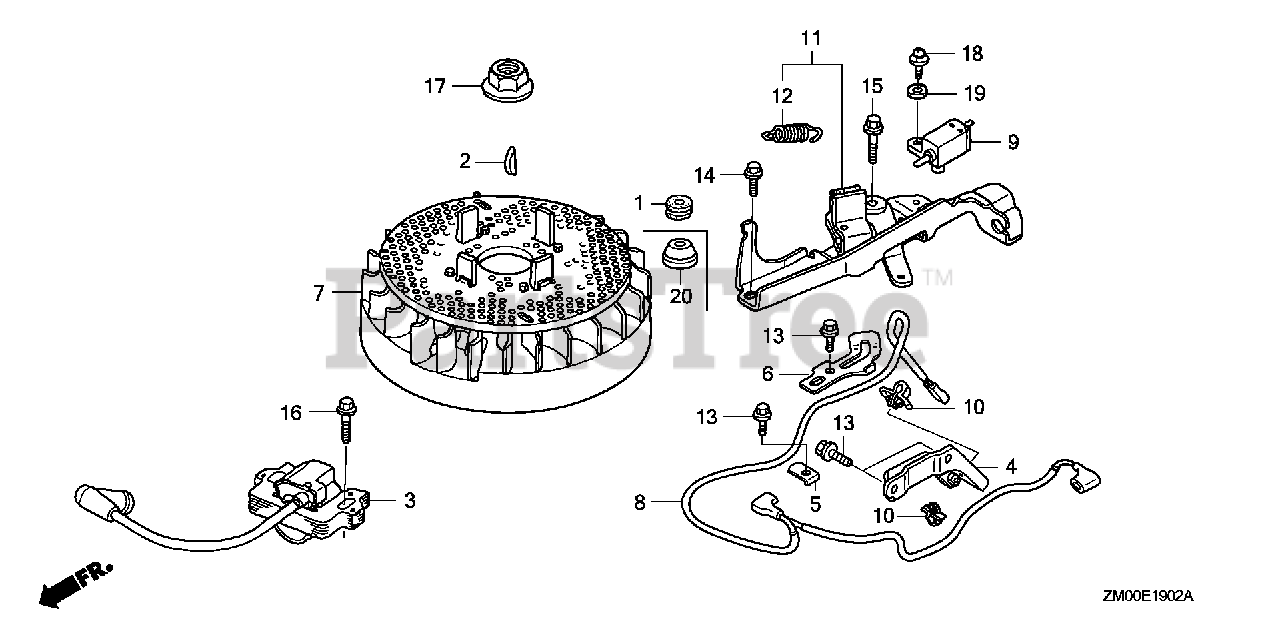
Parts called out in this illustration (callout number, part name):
1	GROMMET A, RR. COVER (8X16X6.6)
2	KEY, SPECIAL WOODRUFF (25X18)
3	COIL ASSY., IGNITION (USE FOR F/W OF TEC) (TEC)
4	CLAMP, STOP SWITCH WIRE
5	CLAMP, STOP SWITCH WIRE
6	CLAMP, WIRE
7	FLYWHEEL ASSY. (TEC) (USE FOR IGN. COIL OF TEC)
8	WIRE, STOP SWITCH
9	SWITCH ASSY., ENGINE STOP (N.C)
10	HOLDER, WIRE (FASTEX)
10	CLIP A, CABLE (3.8MM BLACK) (NIFCO)
11	BRAKE SUB-ASSY.
12	SPRING, BRAKE LEVER
13	BOLT, FLANGE (6X12) (CT200)
14	BOLT, FLANGE (6X14) (CT200)
15	BOLT, FLANGE (6X23) (CT200)
16	BOLT, FLANGE (6X20) (CT200)
17	NUT, SPECIAL (14MM)
18	SCREW-WASHER (4X12)
19	WASHER, PLAIN (4MM)
